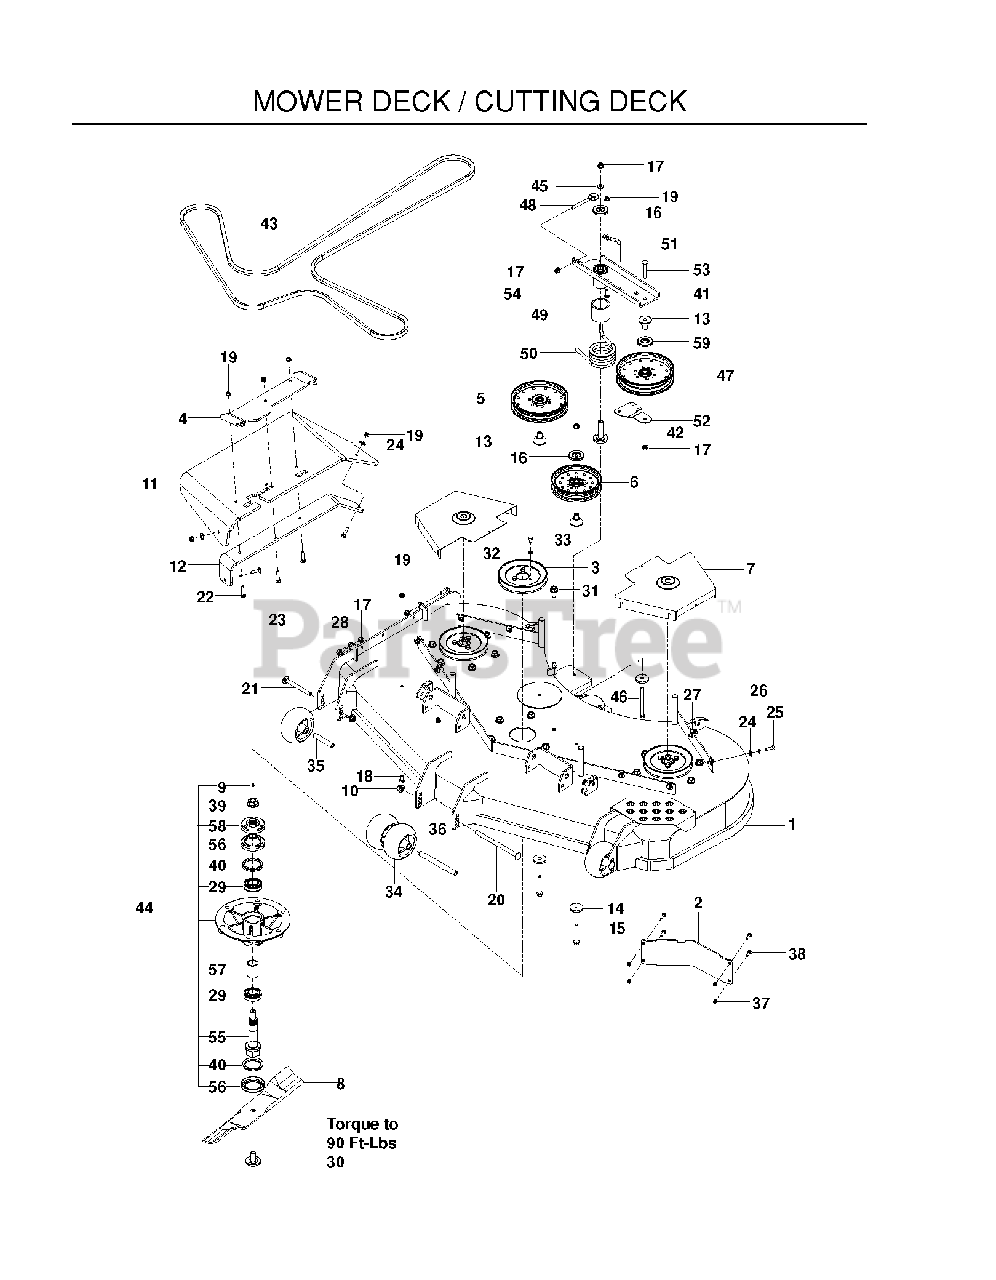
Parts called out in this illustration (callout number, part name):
1	DECK W/SAFETY DECALS 60"
2	BAFFLE, DIVERTER 54"/60" LH
3	PULLEY - 6.57
4	BRKT - CHUTE MTG BLACK
5	PULLEY - 7" NARROW
6	PULLEY IDLER, 6" NARROW
7	SHIELD, BELT, 60" BLUE
9	ZERK
10	NUT, 1/2-13 HEX FLG NYLOC ZD
11	CHUTE, DISCHARGE 48-52
12	BRKT, CHUTE SUPPORT BLACK
13	BEARING, IDLER ARM
14	SPINDLE WASHER
15	HHFS 3/8-16 X 2 3/4
16	DUST SHIELD
17	NUT 3/8-16 HEX FLG NYLOC ZD
18	HHFS 5/16-18 X 3/4
19	5/16-18 NYLOC FLANGE NUT
20	RHSNB 1/2-13 X 8 GR5 ZD
21	RHSNB 1/2-13 X 4.75 GR5 ZD
22	RHSNB 5/16-18 X 1-1/2 GR 5 ZD
23	BOLT, CARRIAGE 5/16X1-1/4
24	WASHER 5/16 FLAT
25	HCS 5/16C X 1
26	WASHER 5/16 LOCK
27	U-CLIP 5/16-18 NUT RETAINER
28	HHFS 3/8-16 X 1 GRD 5 ZD
29	BEARING - 206KRR8
30	BLADE BOLT/WASHER
31	HHFS 1/2-13 X 1 GR5 ZD
32	WASH 5/16 DISC SPRING ZD
33	HCS 5/16-18 X 1/2 GR 5 ZD
34	ROLLER, GAUGE .635 BORN
35	TUBE, ROLLER AXLE
36	TUBE, ROLLER AXLE LONG
37	NUT 1/4-20 NYLOC
39	NUT FLANGE 3/4-16
40	V-RING, 55MM
41	ASSY, IDLER ARM, PZ
42	BEARING, IDLER PIVOT
43	BELT, DECK
44	SPINDLE ASM. 10"
45	WASHER, 3/8 THICK
46	HCS 3/8-16 X 4-1/2 GR 8 ZD
47	PULLEY - IDLER 7"
48	EYE BOLT, 3/8 X 4"
49	SPACER, IDLER PIVOT
50	SPRING, TORSION, IDLER
51	BELT KEEPER
52	BELT GUIDE, BLK
53	CARRIAGE BOLT 3/8-16 X
54	RHSSNB 5/16C X 1.0
55	SHAFT - SPINDLE
56	CUP - DEBRIS
57	SPACER - BEARING
58	HUB - PULLEY
59	SHIELD, DUST
